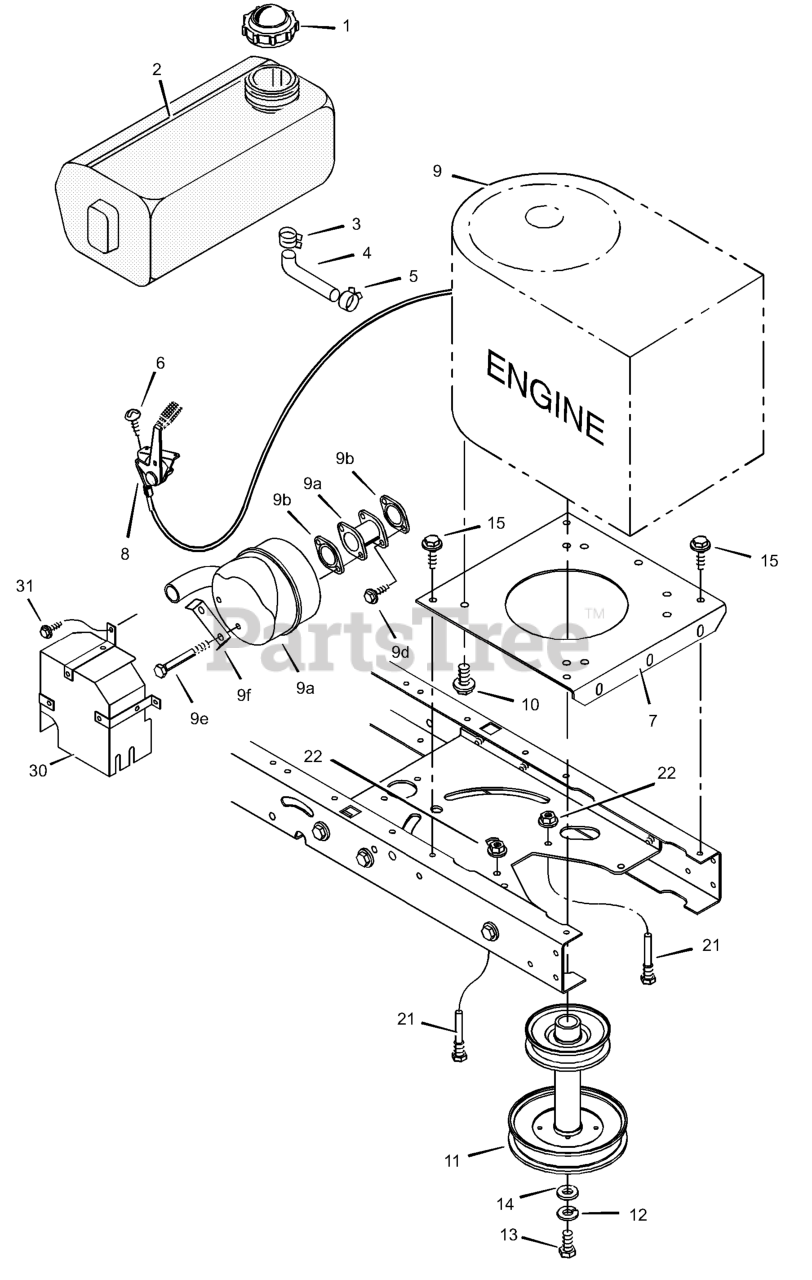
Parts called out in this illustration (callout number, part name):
1	Fuel Cap
2	TANK, Fuel 1.4 Gal.
3	Hose Clamp
4	Fuel Line (Must cut to length)
5	Hose Clamp
7	Plate, Engine
8	Throttle Control
9	Engine
9A	Muffler
9B	GASKET, Exhaust
9C	Adapter, Muffler
9D	Screw, Adapter
9E	Bolt, Muffler
9F	Lock, Screw
10	Bolt, Engine Mount
11	STACK PULLEY ASSEMBLY
12	Lockwasher
13	Bolt, Hex
21	Guide, Belt
22	Nut, Flange
30	Shield, Heat
